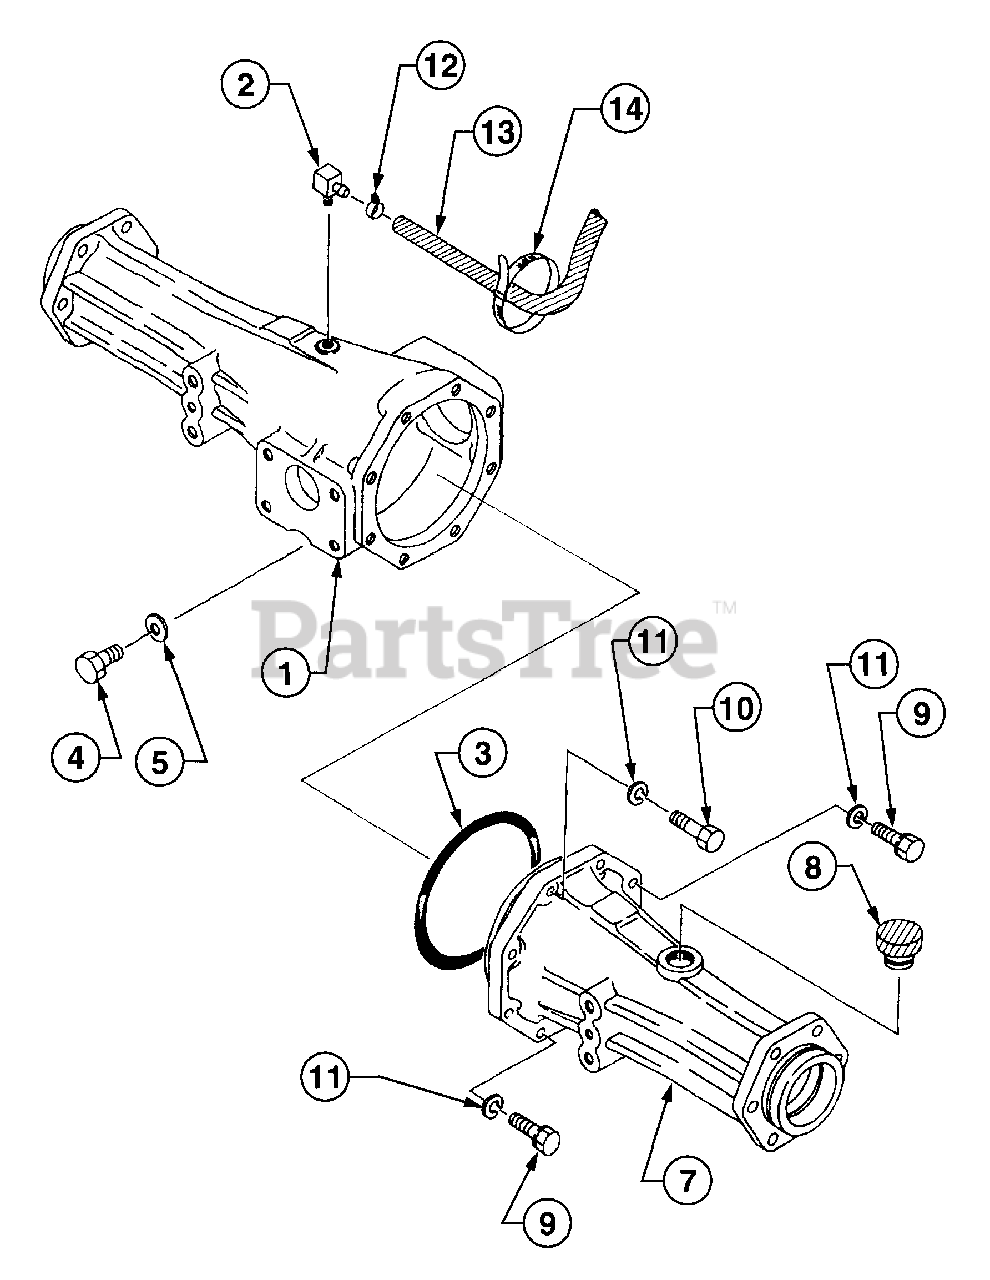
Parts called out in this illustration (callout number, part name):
1	Case R.H., Center
5	Washer, Seal
7	Case L.H., Center
11	Washer, Spring
